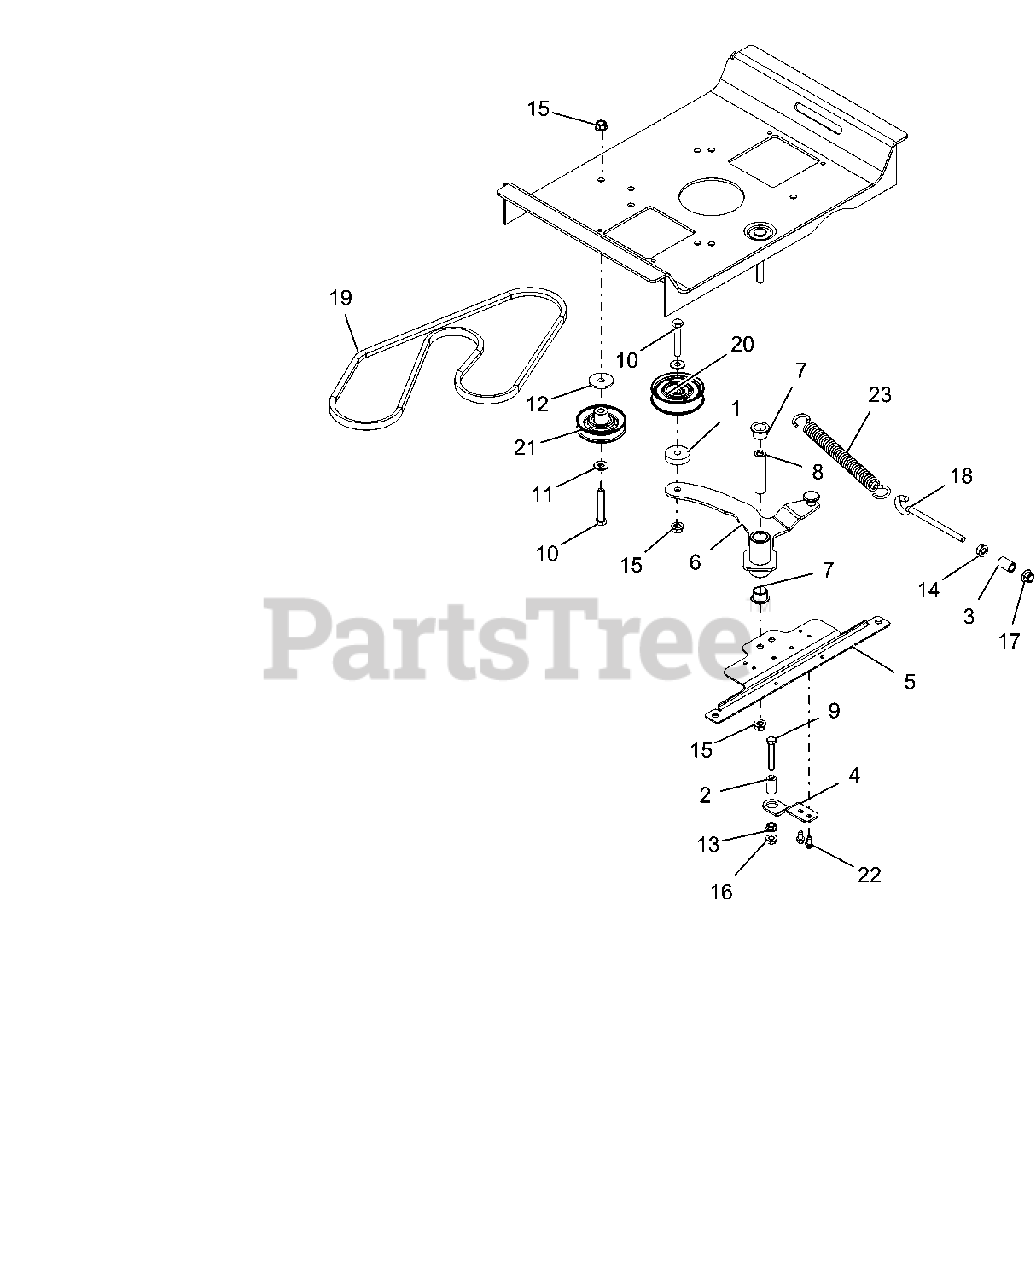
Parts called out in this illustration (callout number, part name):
1	SPACER, .39 X 1.50 X .380
2	SPACER, RUBBER 5/16 IDX1.0 LG
3	SPACER, .375X.625X.970 (PM)
4	BRKT, CLUTCH STOP
5	BRKT, DRIVE IDLER MOUNTING
6	WLDMT,GRD DRIVE IDLER ARM-LGR
7	BSHG-FLG 0.75X0.875X.625X1.125
8	BUSHING, SLEEVE .38X.750X2.78
9	@BLT-HEX .31-18X2.00 GR5 YWZC
10	@BLT-HEX .38-16X2.25 GR5 YWZC
11	@WSHR-FL-STL.38X.875X.083 YWZC
12	WSHR-FL-STL .380X1.50X.125YWZC
13	@NUT-SPNLK-FLG .312-18 YWZC
14	@NUT-SPNLK-FLG .375-16 YWZC
15	@NUT-LK-TOP-FLG .38-16 YWZC
16	@NUT-LK-TOP-FLG .31-18 YWZC
17	@NUT-LK-NYL-FLG .38-16 YWZC
18	BOLT,.38-16 X 4.25-.62 DIA EYE
19	V-BELT, A-RAW EDGE
20	IDLER, FLAT - 3.05" X .75"
21	ASM, 3.00" V IDLER
22	SCR-TAP .25-20X.50 HWH TR YWZ
23	SPRING, EXTENSION
